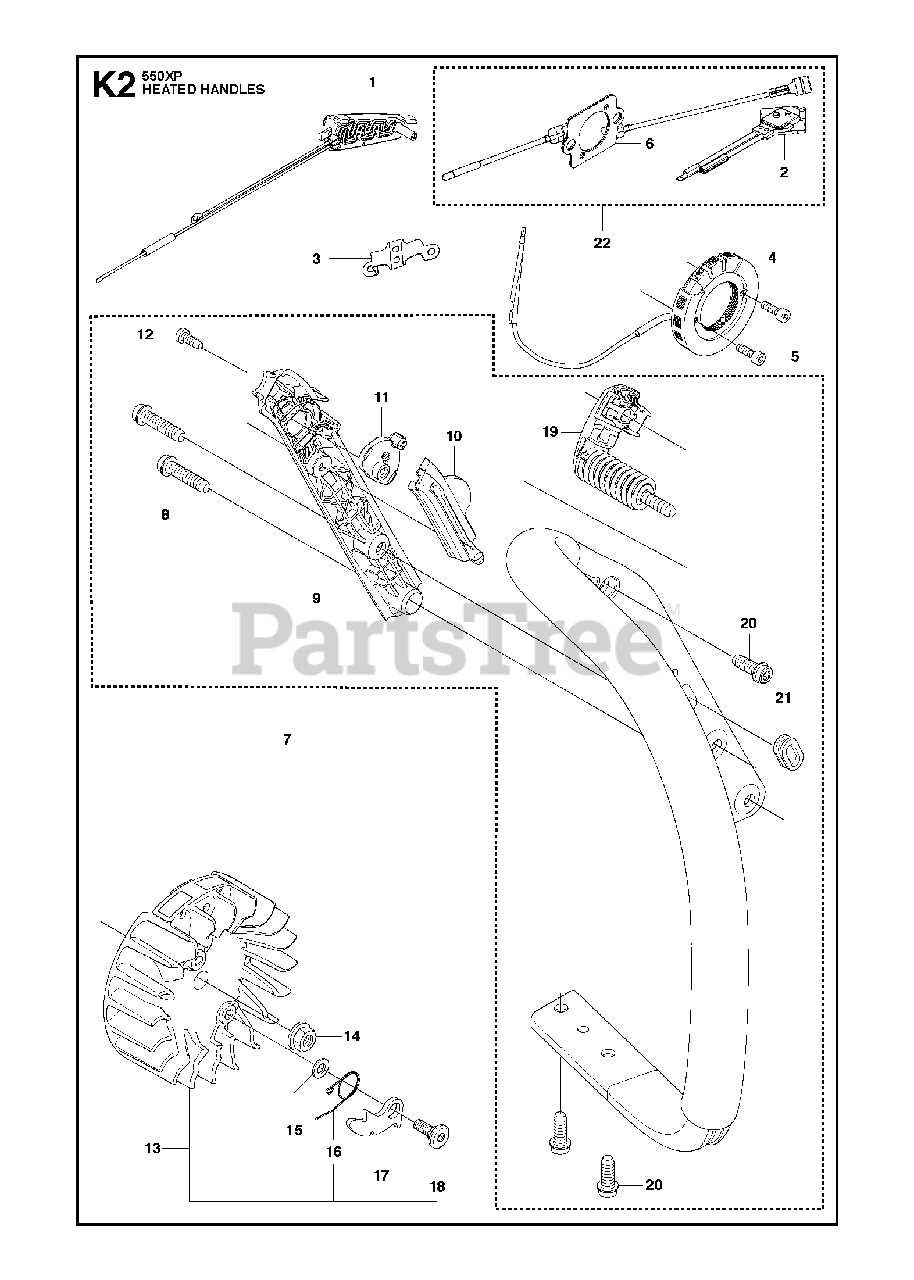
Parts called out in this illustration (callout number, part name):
1	HANDLE INSERT
2	THERMOSTAT ASSY
4	GENERATOR STATOR
6	Foil Element
7	FRONT HANDLE
8	SCREW
9	COVER
10	CONTACT PLATE
11	HANDLE
12	SCREW
13	FLYWHEEL ASSY
14	NUT W/ WASHER
15	WASHER
16	SPRING
17	PAWL
18	SCREW M5X14
19	ANTIVIBRATION ELEMENT
20	SCREW IHSCFT
21	GROMMET
22	THERMOSTAT ASSY
